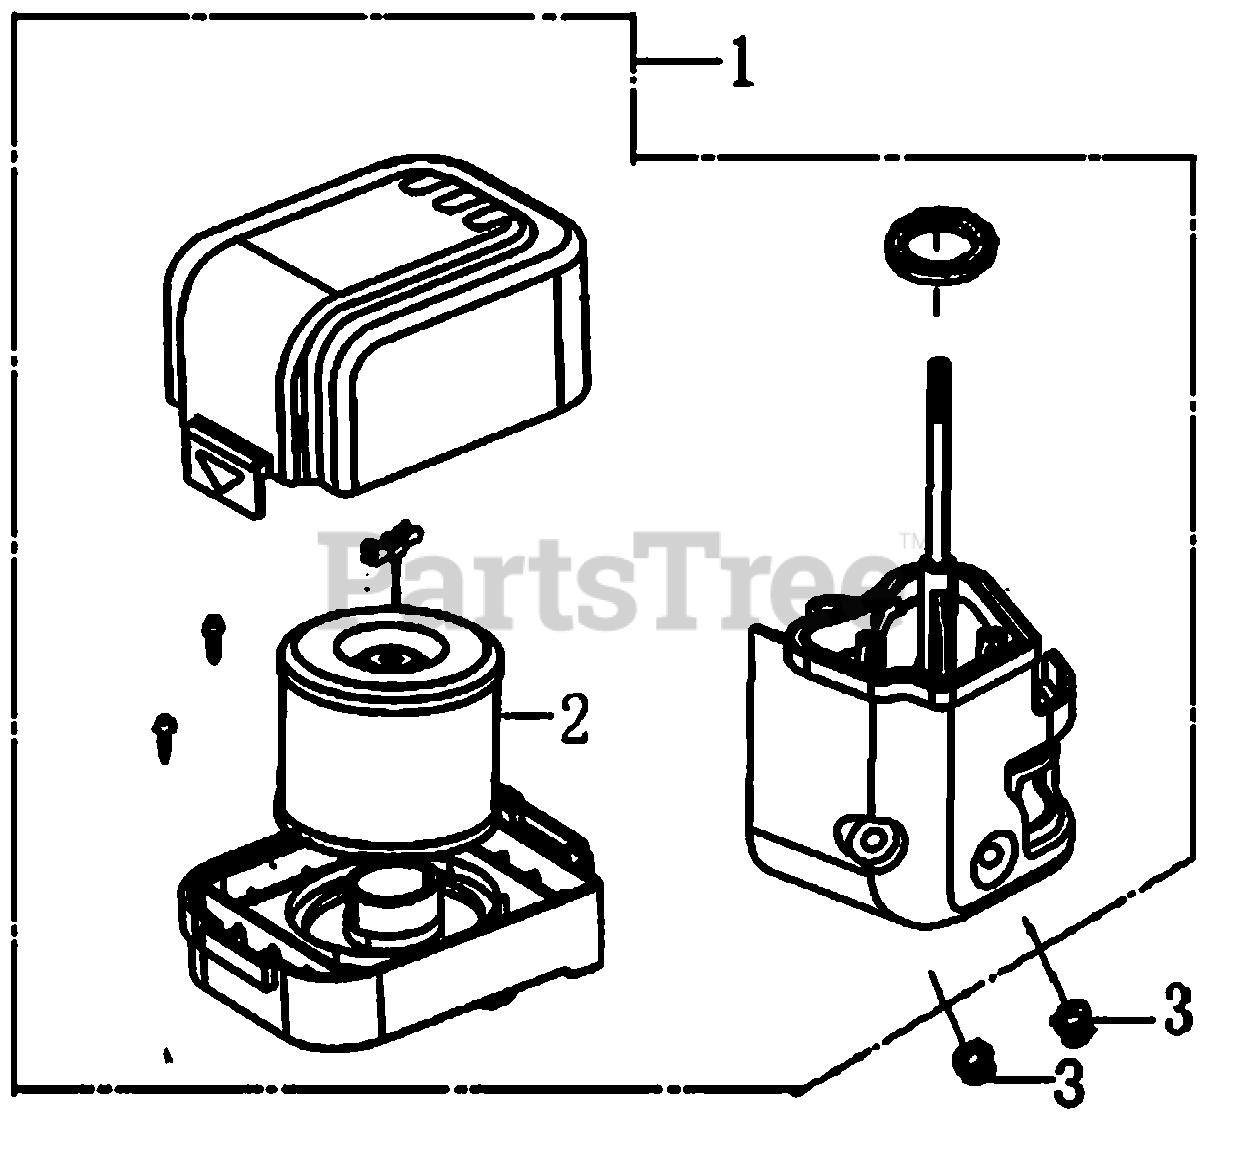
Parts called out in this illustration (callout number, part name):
1	AIR CLEANER ASSY
2	ELEMENT, AIR FILTER
3	NUT, FLANGE 6MM
